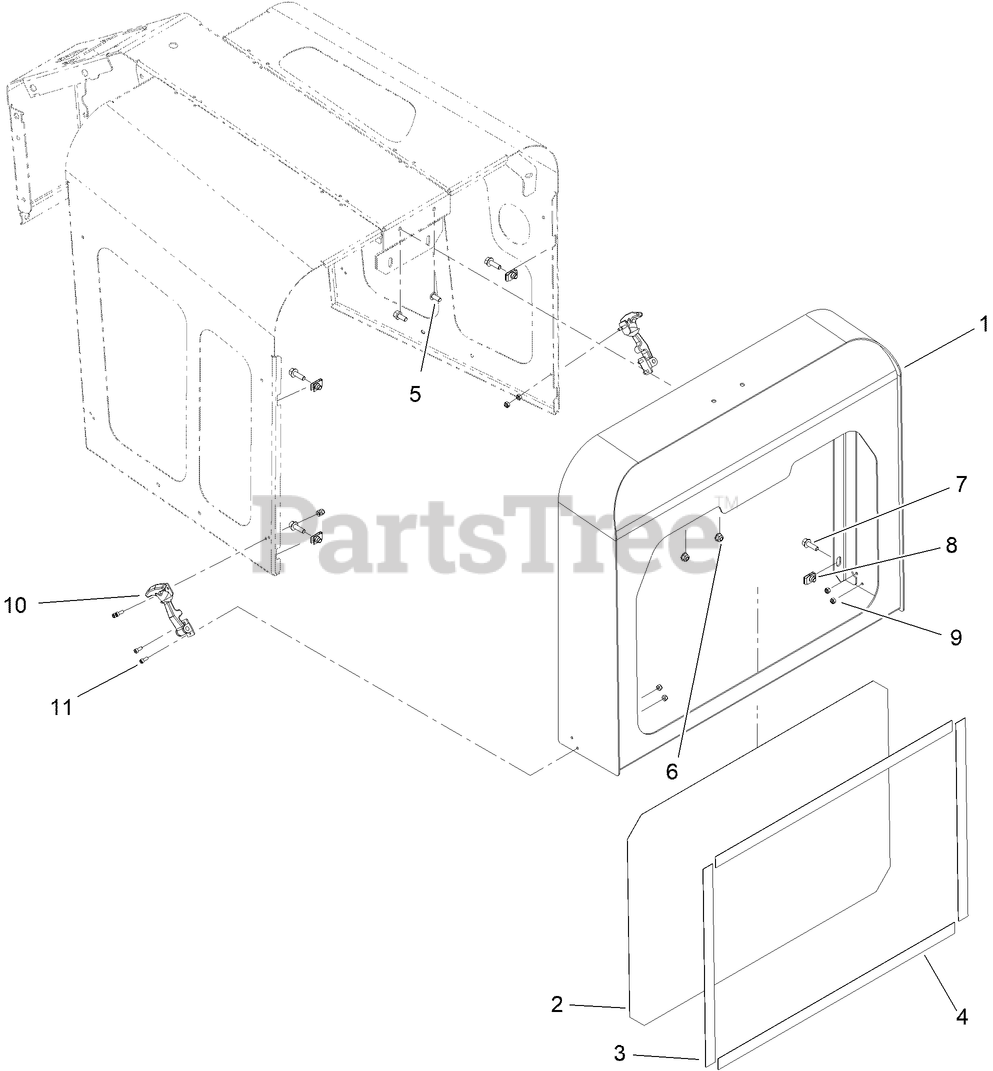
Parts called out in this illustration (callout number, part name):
1	GRILL (TORO RED)
2	SCREEN-GRILL
3	VHB TAPE (1.0") HIGH ENERGY
4	VHB TAPE (1.0") HIGH ENERGY
5	SCREW-HHF
6	NUT-HF, NI
7	SCREW-HHF
8	NUT-U
9	NUT-LOCK, NI
10	LATCH-FLEX, DRAW
11	SCREW-HSH
